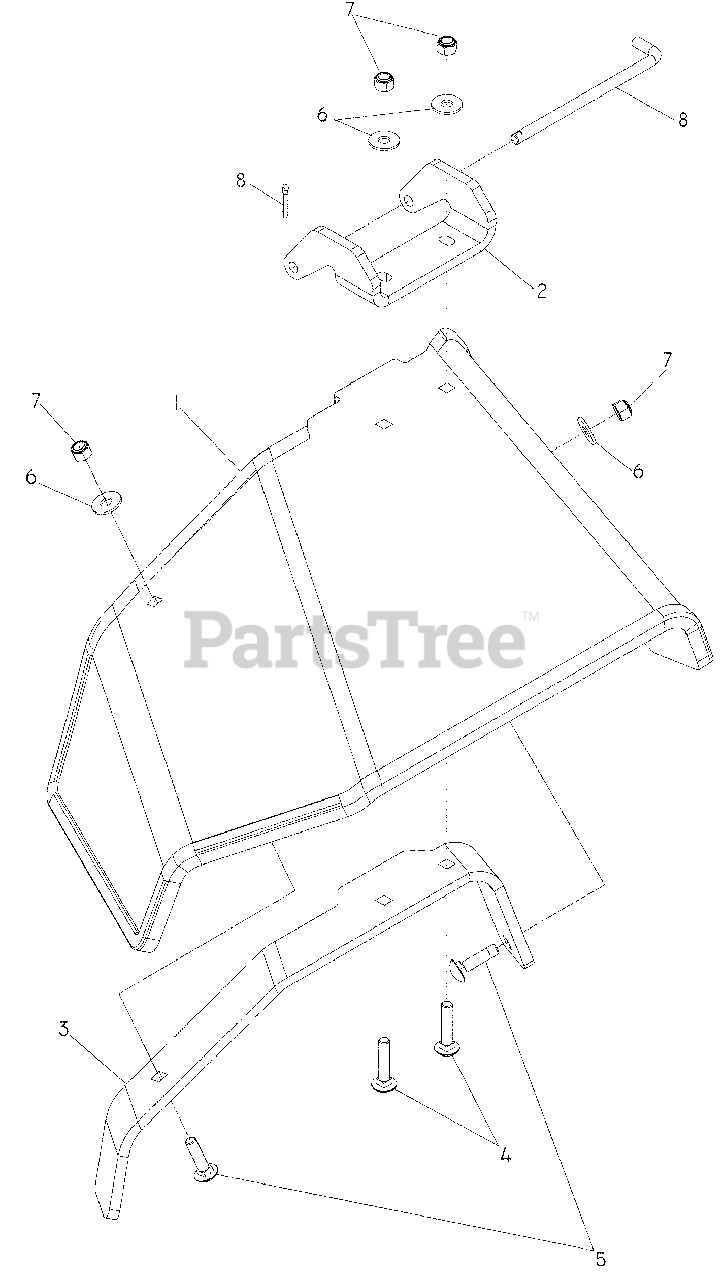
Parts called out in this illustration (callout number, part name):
1	DISCHARGE CHUTE, 52-61
2	MOUNTING BRACKET
3	BRCKT REINFRCMNT, 52-61
4	RHSNB 5/16-18 x 1½
5	RHSNB 5/16-18 X 1¼
6	WASHER, 5/16 STD FLT
7	NUT 5/16-18 HEX NYLOC
8	PIN, CHUTE PIVOT
